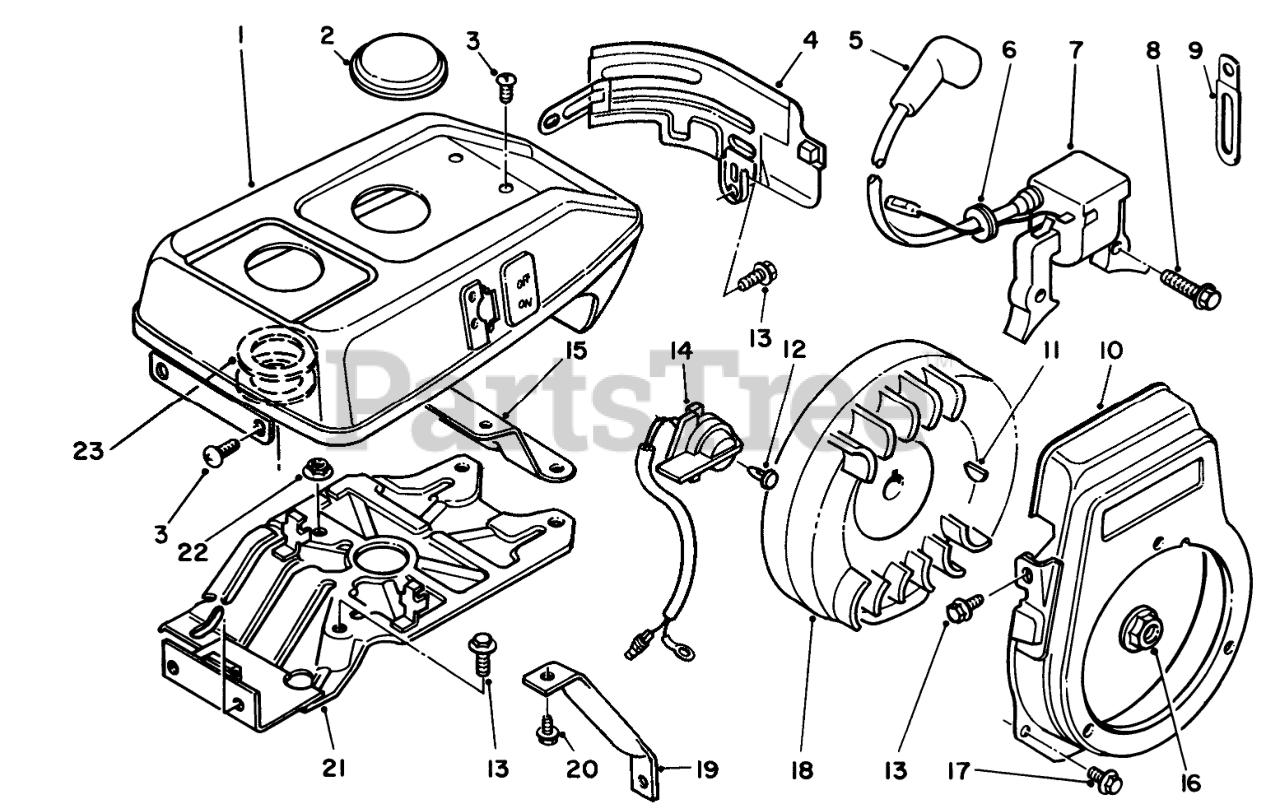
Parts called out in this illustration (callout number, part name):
1	Cover-Engine
3	Screw-Round Phillips Hd.
4	Cowling-Side
5	CAP-SPARKPLUG
6	Grommet
7	Magneto Assembly (Incl. Ref. #5 & 6)
9	CLAMP
10	Cover-Cooling Fan
14	Switch-Engine
15	Bracket-Engine Cover
18	Rotor
19	Support-Fuel Tank
20	SCREW-HHF
21	Cowling-Upper
23	Washer
